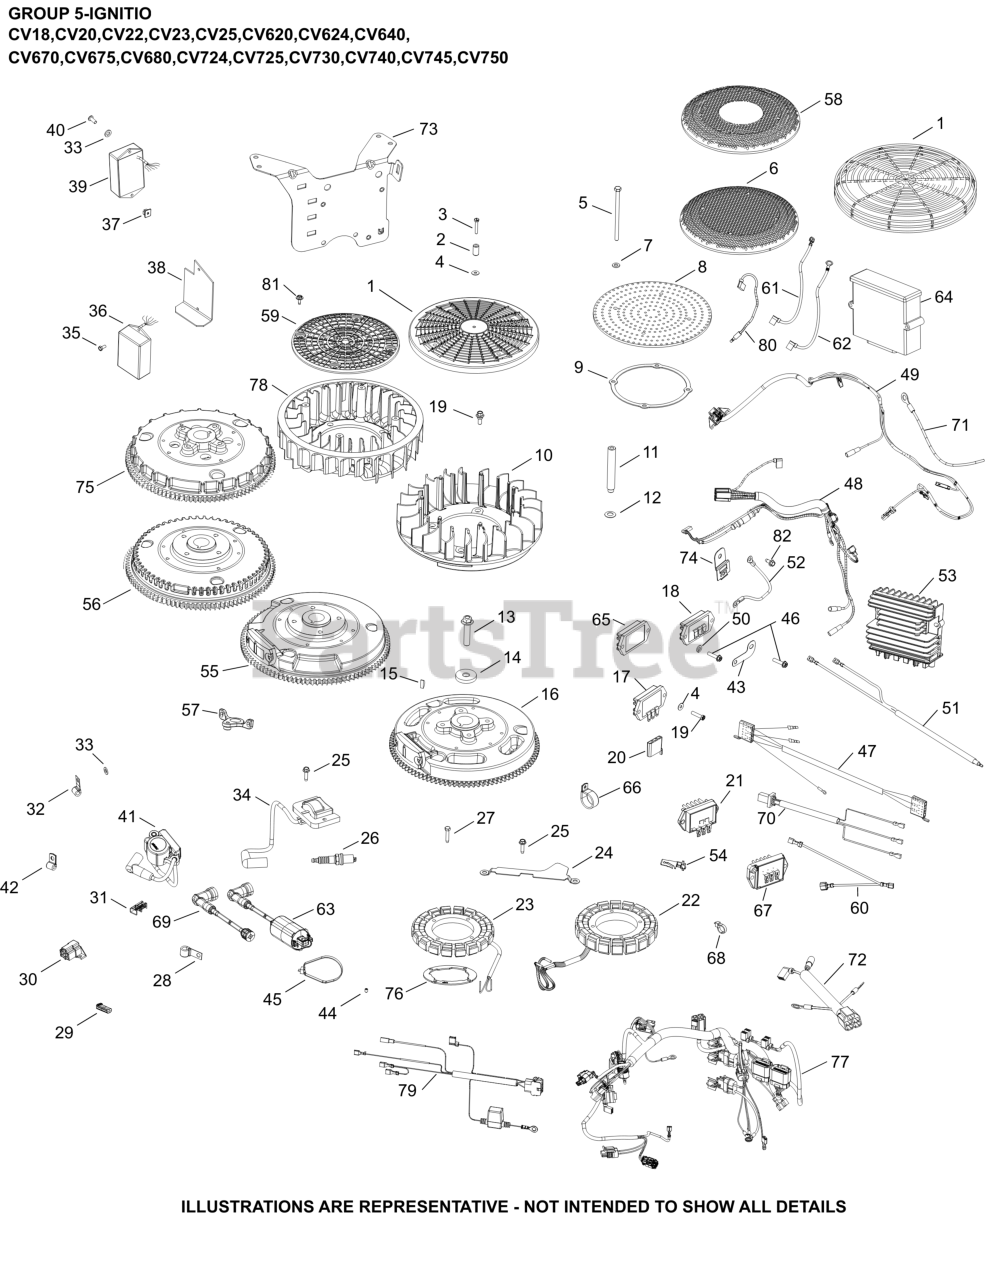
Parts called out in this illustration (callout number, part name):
5	SCREW, CAP M6X1.0X99.5
6	SCREEN, GRASS
7	WASHER, FLAT 1/4" (O.D. 5/8")
9	RING, SUPPORT
12	WASHER, SPRING 10 MM
13	SCREW, FLG M10X1.5X45-USE 25 086 361-S
14	WASHER, FLAT 13/32"
15	KEY, 3/16" X 5/8"
16	FLYWHEEL ASSEMBLY (LW)
18	REGULATOR/RECT 12/15A (41 403 10-S)
20	CONNECTOR
23	KIT, 15 / 20 AMP STATOR
25	SCREW, THREAD FORMING
26	PLUG, SPARK (STD)
27	SCREW, THREAD FORMING
28	CLIP, CABLE
33	WASHER, FLAT 1/4" (O.D. 1/2")
34	MODULE,IGNITION
34	MODULE,MDI
34	MODULE, MDI
39	MODULE,DSAM CONTROL-DISC-SEE PB 259
41	MODULE,DSAI IGNITION-DISC-SEE PB 259
44	SCREW, SKT SET #10-24X1/4"
46	SCREW, HEX FLANGE HI-LO
48	HARNESS, WIRING-USE 24 176 185-S
48	HARNESS, WIRING ASSEMBLY
50	WASHER, LOCK
51	LEAD, DUPLEX ASSEMBLY
NI	KIT,DSAI CONVERSION-DISC-SEE PB 259
NI	KIT,MDI MODULE CONVERSION-SEE PB 259
